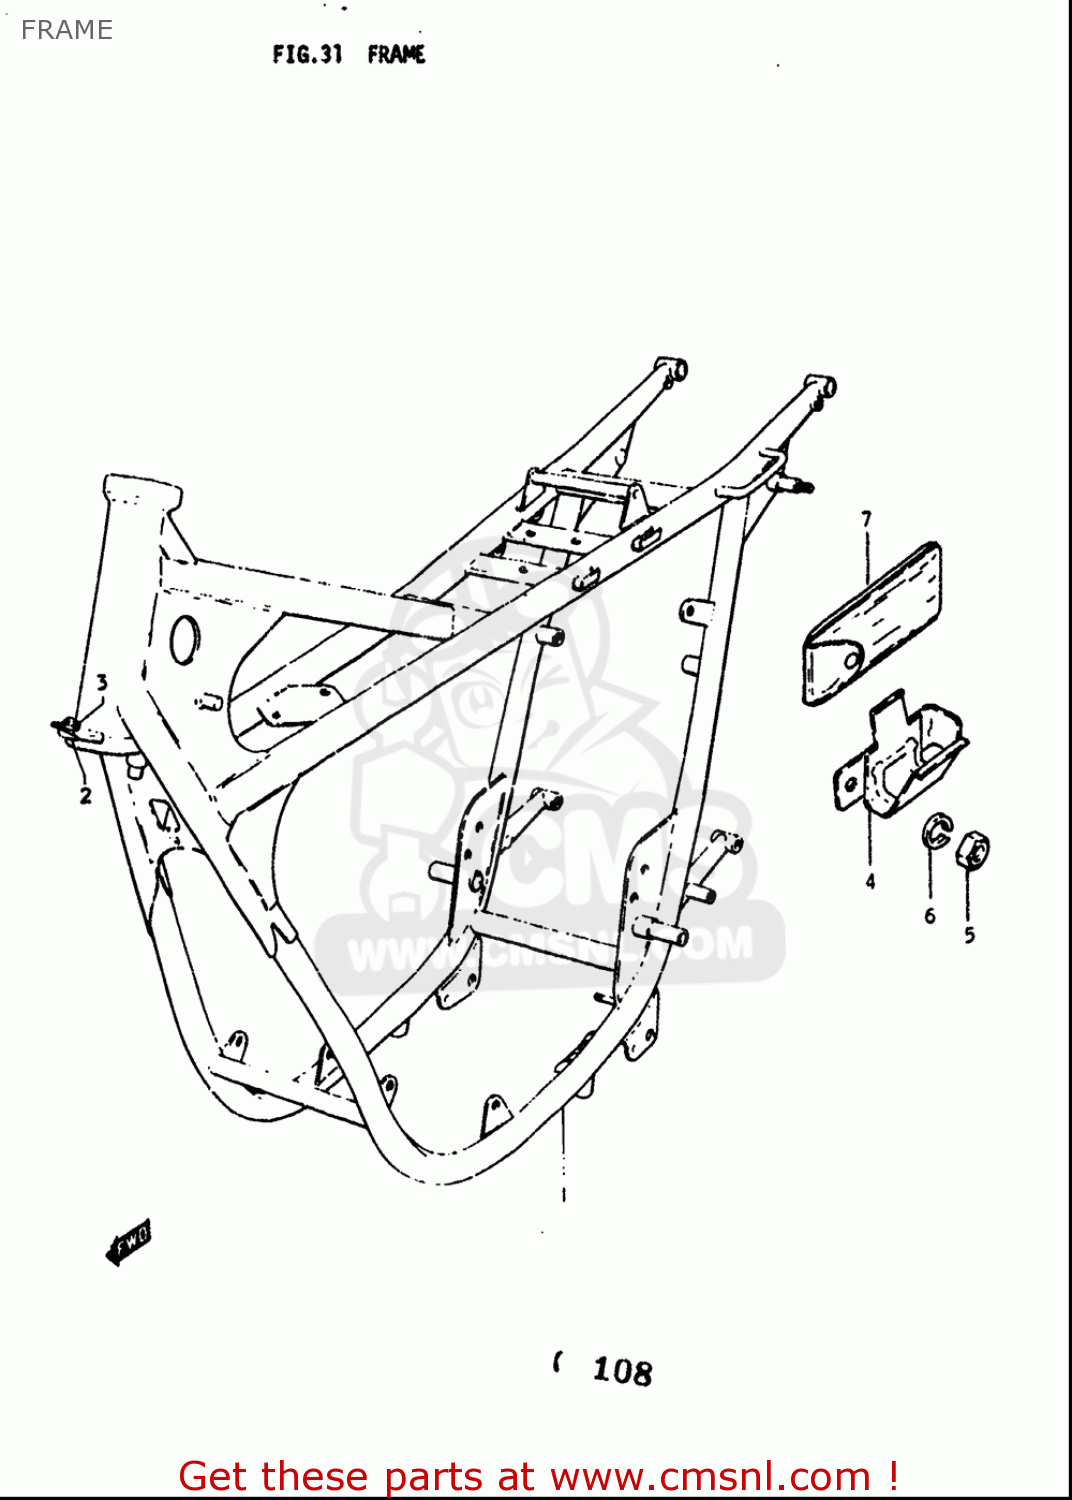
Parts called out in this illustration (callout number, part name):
3	NUT
5	NUT
6	WASHER,LOCK
